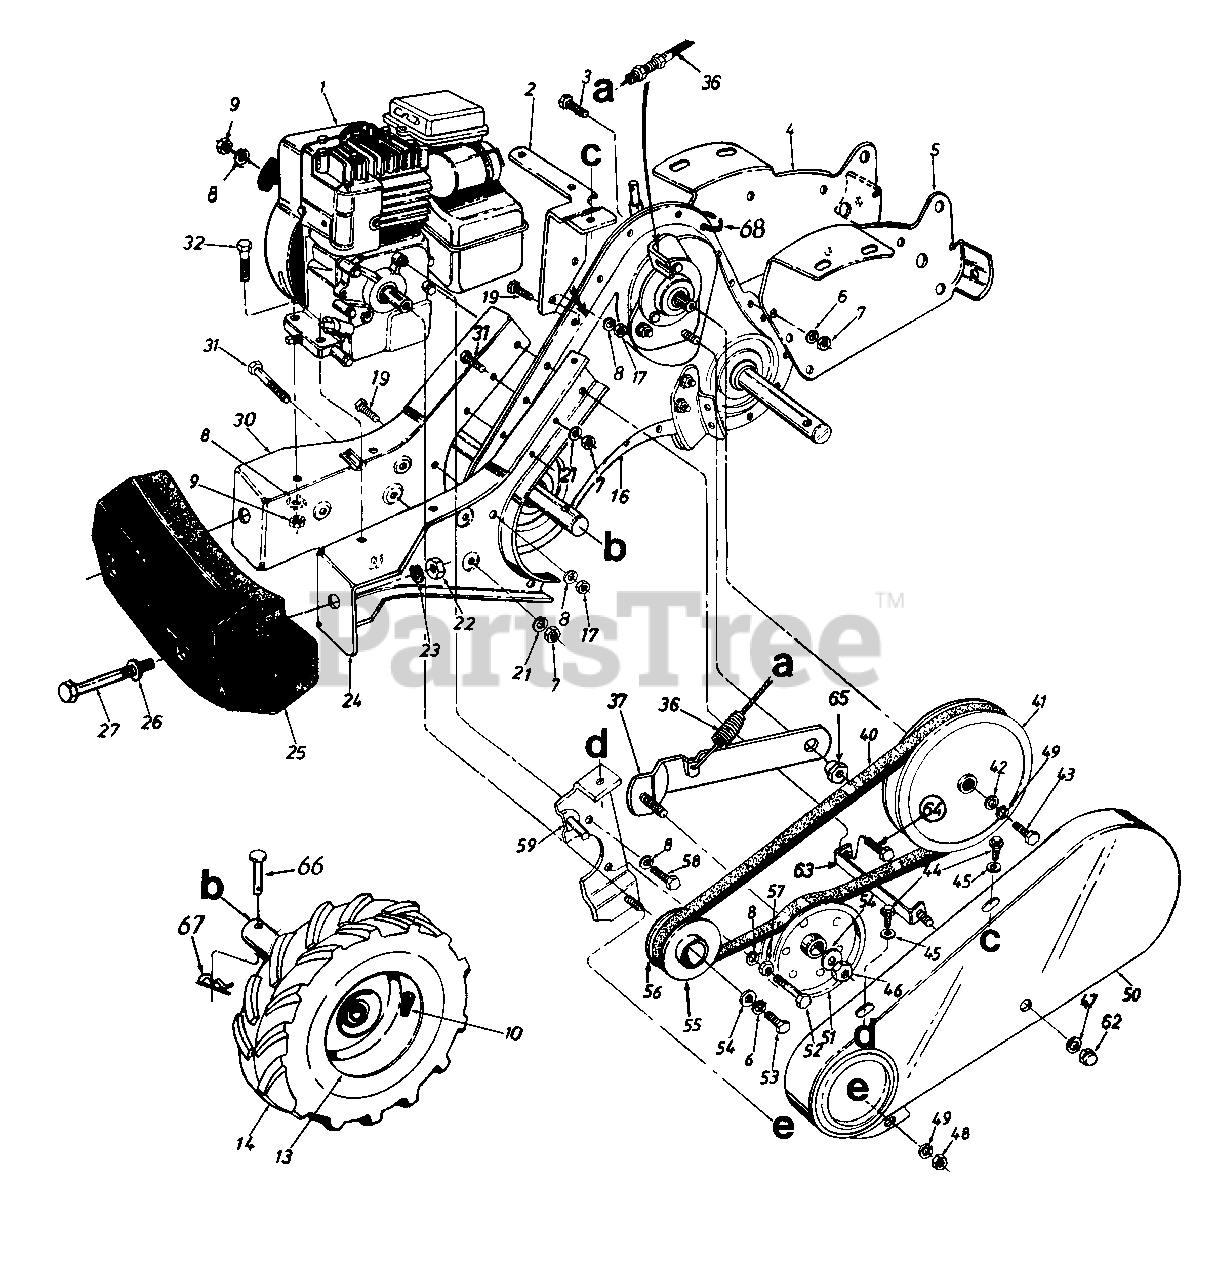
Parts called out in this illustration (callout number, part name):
1	Engine
7	Hex Nut 3/8-16 Thd.
8	L-Wash. 5/16" I.D.
9	Hex Nut 5/16-18" Thd.
10	Air Valve
16	Gear Case Ass'y. Comp.
17	Hex Nut 5/16-18 Thd.
19	Hex Bolt 5/16-18 x .75" Lg.
21	L-Wash. 3/8" I.D.- H.D.
22	Hex Nut 1/2-13 Thd.
23	L-Wash. 1/2" I.D.
26	Fl-Wash. .510" I.D. x 1.0"
27	Hex Bolt 1/2-13 x 5.00" Lg.
32	Hex Bolt 5/16-18 x 1.50"
36	Clutch Control Cable 46" Lg.
37	Idler Bracket Ass'y.
40	"V"-Belt
41	Fl-Pulley 8" O.D.
42	Fl-Wash. 1/4" I.D. x .93" O.D.
43	Hex Bolt 1/4-28 x .75" Lg.
44	Hex Wash. Hd. S-Tap Scr. 1/4-20 x .50" Lg.
45	Fl-Wash. .281" I.D. x .625"
46	Hex Cent. L-Nut 3/8-24 Thd.
47	Fl-Wash. .266" I.D. x .625" O.D.
48	Hex Nut 1/4-20 Thd.
49	L-Wash. 1/4" I.D.
51	Fl-Idler w/Flanges 3.75" O.D.
52	Hex Bolt 5/16-24 x 1.75"
53	Hex Bolt 3/8-24 x 1.00" Lg.
54	Fl-Wash. 3/8" I.D. x 1.00"
55	Outer Engine Pulley Half
56	Inner Engine Pulley Half
57	Hex Nut 5/16-24 Thd.
58	Hex Bolt 5/16-24 x .62" Lg.
63	Belt Cover Brkt. Ass'y.
64	Hex Bolt 5/16-18 x 1" Lg. (Gr. 5)
65	Shld. Nut
66	Clevis Pin
67	Hairpin Clip
68	Cable Tie - Self Clinching
